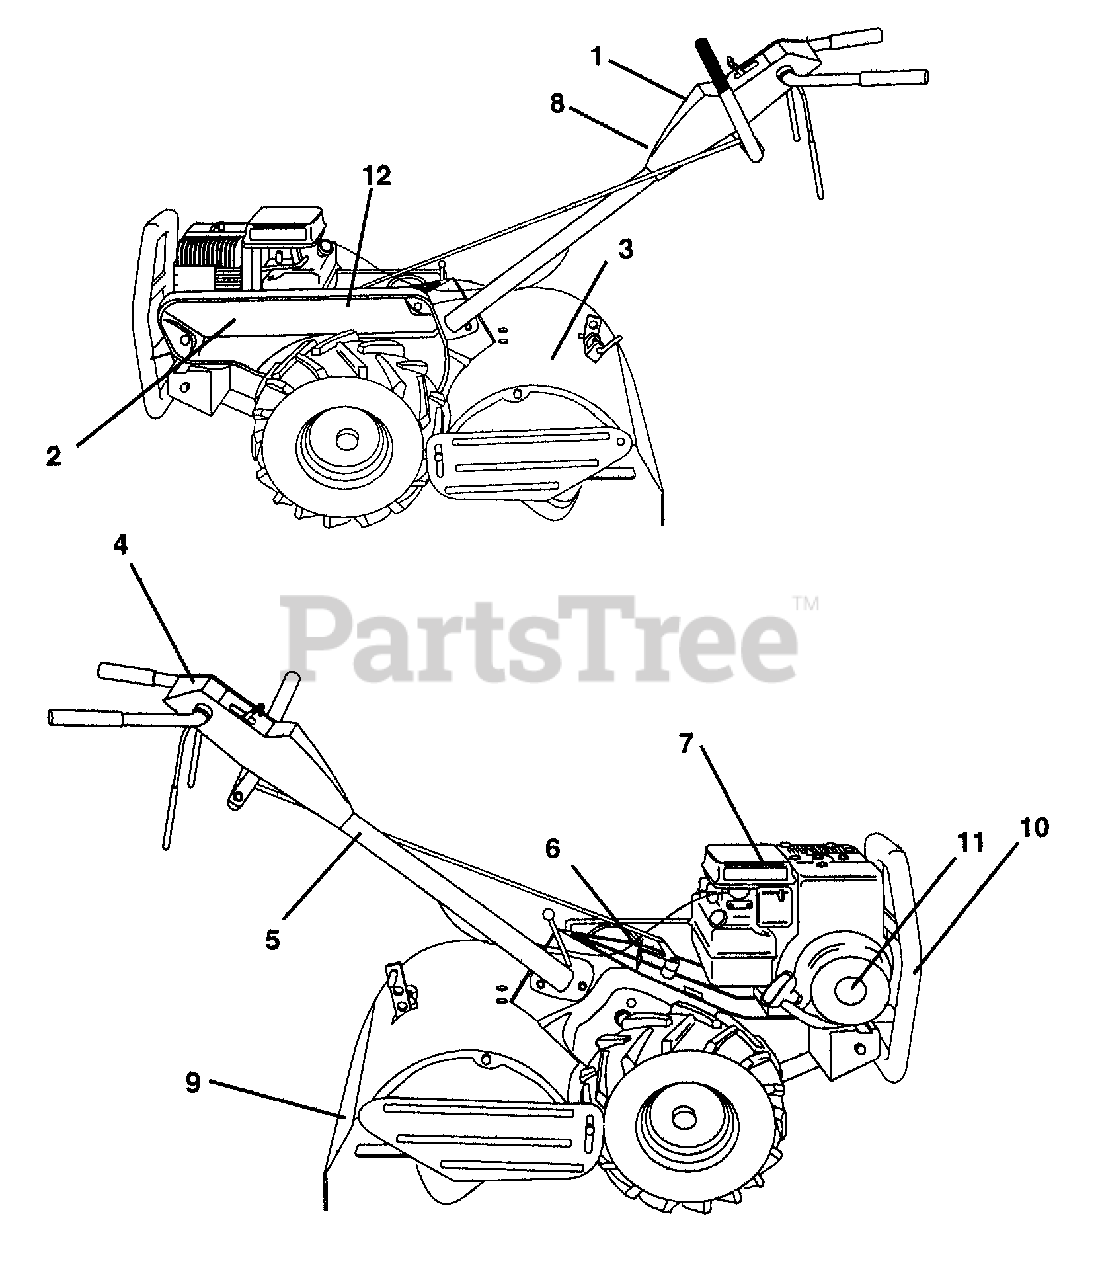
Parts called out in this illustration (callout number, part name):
1	Decal, Logo
2	Decal, Logo
3	Decal, Logo
4	Decal, Instruction, Tilling
5	Decal, Hand Placement (AYP part number)
6	Decal, Shift Indicator (AYP part number)
7	Decal, Caution (AYP part number)
8	Decal, Control Panel 5.5 HP
9	Decal, Warning, Rotating Tines (AYP part number)
10	Decal, Bumper/Grille
11	Decal, Engine
12	Decal, Cust Assist
